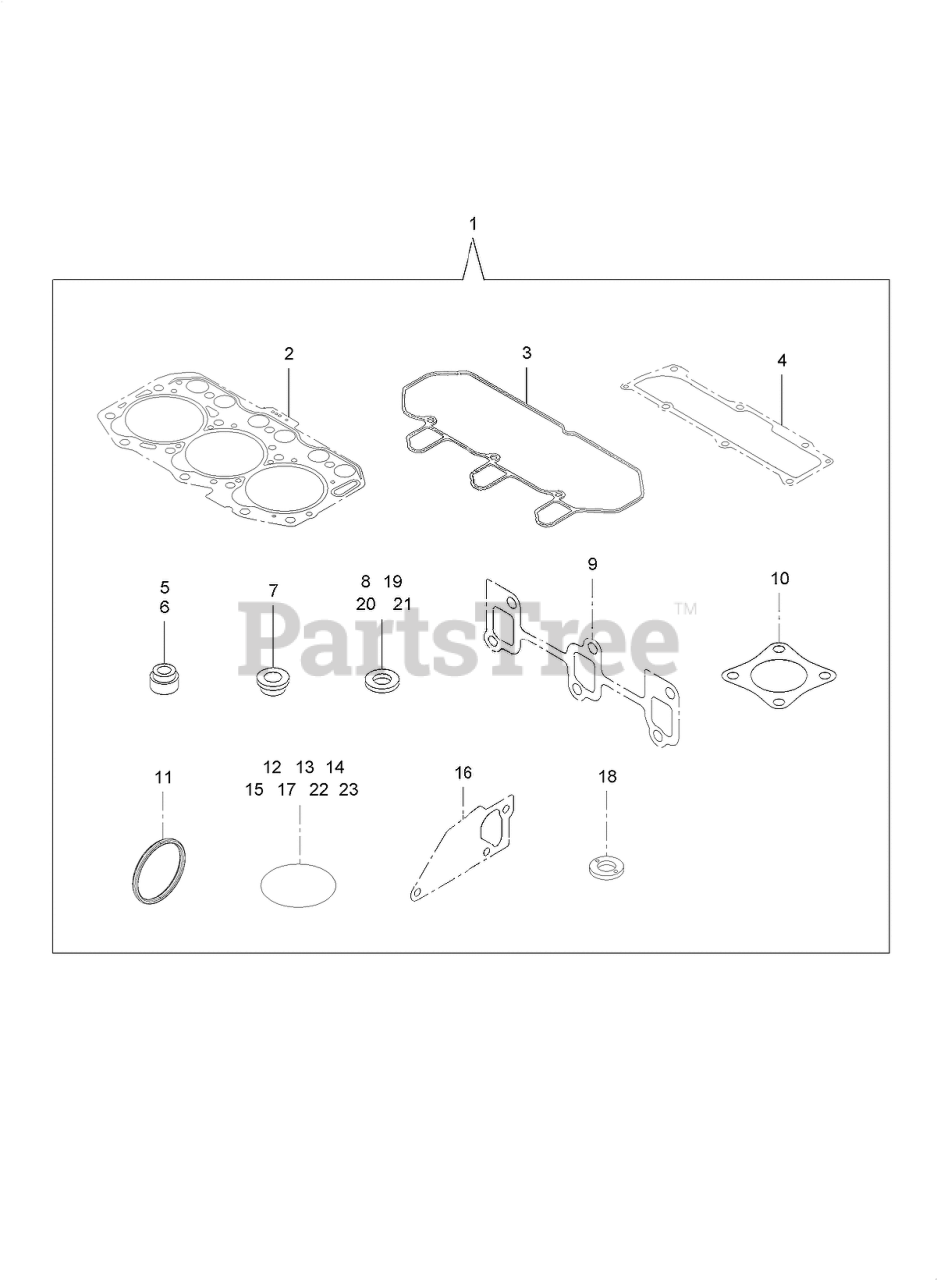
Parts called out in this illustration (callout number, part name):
1	GASKET KIT
2	GASKET SET-HEAD
3	GASKET-BONNET
5	SEAL-STEM, VALVE
6	SEAL-STEM, VALVE
7	PROTECTOR-NOZZLE
8	GASKET-NOZZLE
9	GASKET-EXH MANIFOLD
10	GASKET-SILENCER
11	GASKET-WASHER
16	GASKET-WATER PUMP
19	WASHER-SEAL
20	WASHER-SEAL
